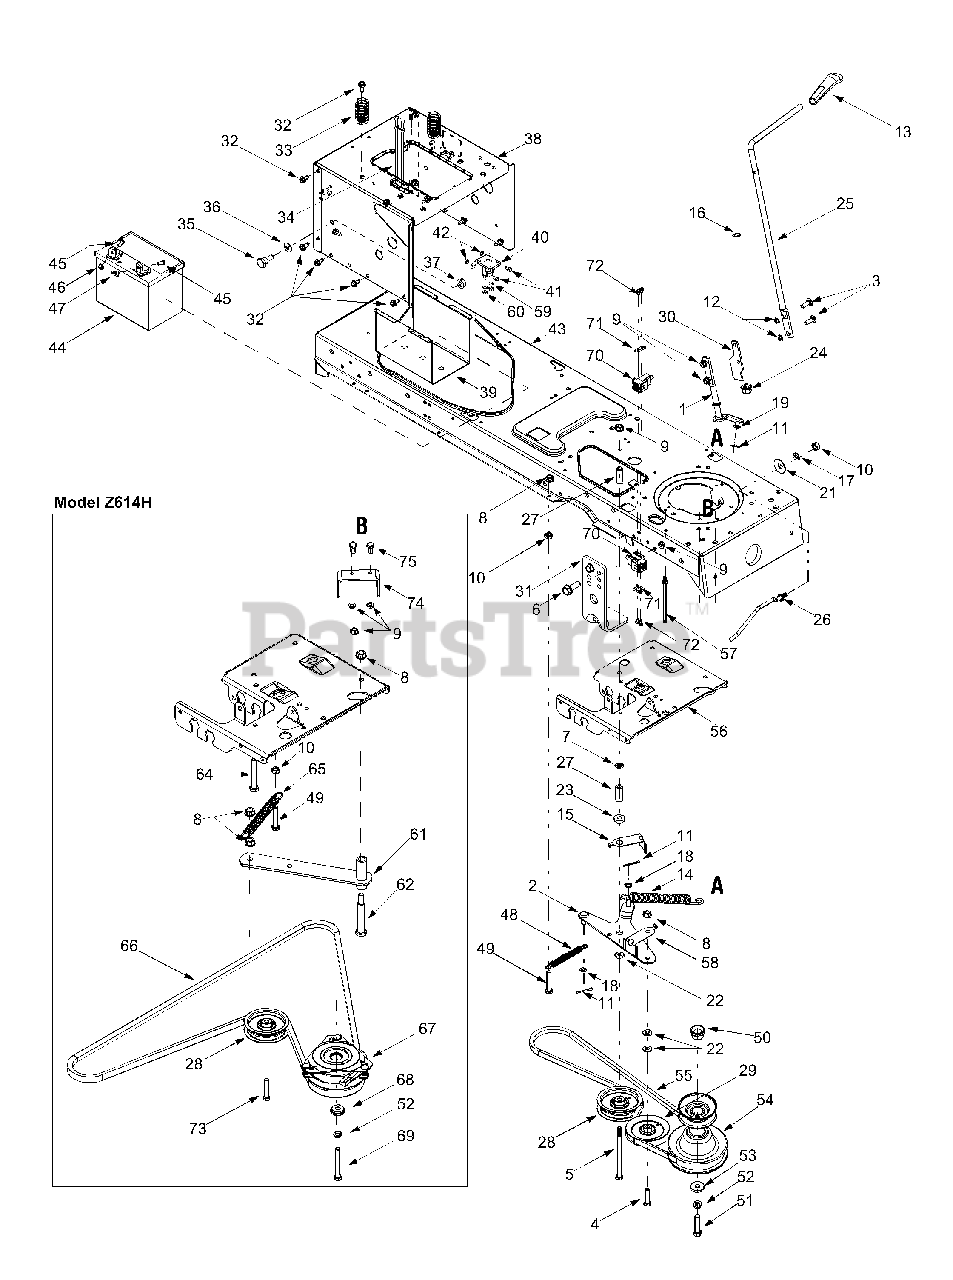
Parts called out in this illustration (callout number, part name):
1	PTO Engage Lever Assembly
4	Hex Cap Screw, 3/8-16 x 1.5
5	Hex Cap Screw, 3/8-16 x 5.5
6	Hex Head Washer Screw, 5/16-18 x .875
7	Push Nut, 3/8
8	Flange Lock Nut, 3/8-16
9	Flange Lock Nut, 5/16-18
10	Hex Nut, 5/16-18
11	Cotter Pin, 1/8 x 1.25
12	Speed Nut, .3125
13	PTO Knob
14	Extension Spring, .75 x 6.75
15	Belt Guard
16	Flat Washer, .510 x .750 x .033
17	Lock Washer, 5/16
18	Flat Washer, .385 x .62 x .063
19	Flat Washer, 5/16
21	Bell Washer, .39 x 1.13 x .062
22	Flat Washer, .407 x .812 x .135
23	Shoulder Spacer, .380
24	Hex Split Flange Bearing, .5
26	Belt Keeper Rod
27	Spacer, 3/8 x 1.54
28	Idler Pulley, 3.5
29	Idler Pulley, 4.0
32	Self-Tapping Screw, 5/16-18 x .625
33	Compression Spring, 1.28 x 3.25
34	Battery Strap
35	Shoulder Screw, .625 x .5, 7/16-20
36	Bell Washer, .45 x 1.0 x .062
37	Flange Lock Nut, 7/16-20
41	Self-Tapping Screw, 1/4-20 x .5
42	Lock Washer, 1/4
45	Hex Cap Screw, 1/4-20 x .62
46	Hex Sems Nut, 1/4-20
47	Wing Nut, 1/4-20
48	Extension Spring, .50 x 5.0
49	Hex Cap Screw, 5/16-18 x 1.75
50	Spacer Cup
51	Hex Head Cap Screw, 7/16-20 x 1.25
52	Lock Washer, 7/16
53	Flat Washer, .450 x 1.25
54	Engine Pulley, 3.56 OD x 5.56
55	PTO Belt
57	Keeper Pin, 5/16 x 4.75
58	Belt Guard
59	Lock Washer
60	Hex Nut
62	Shoulder Screw 1/2 x 2.50
64	Hex Screw 3/8-16 x 2.5
65	Extension Spring
66	PTO Belt (Model Z614H)
67	Electric PTO Clutch (Model Z614H)
68	Shoulder Spacer
69	Hex Cap Screw
70	Switch
71	Switch Plate
72	Screw #10-16 x 0.5
73	Hex Cap Screw 3/8-16 x 2.0
